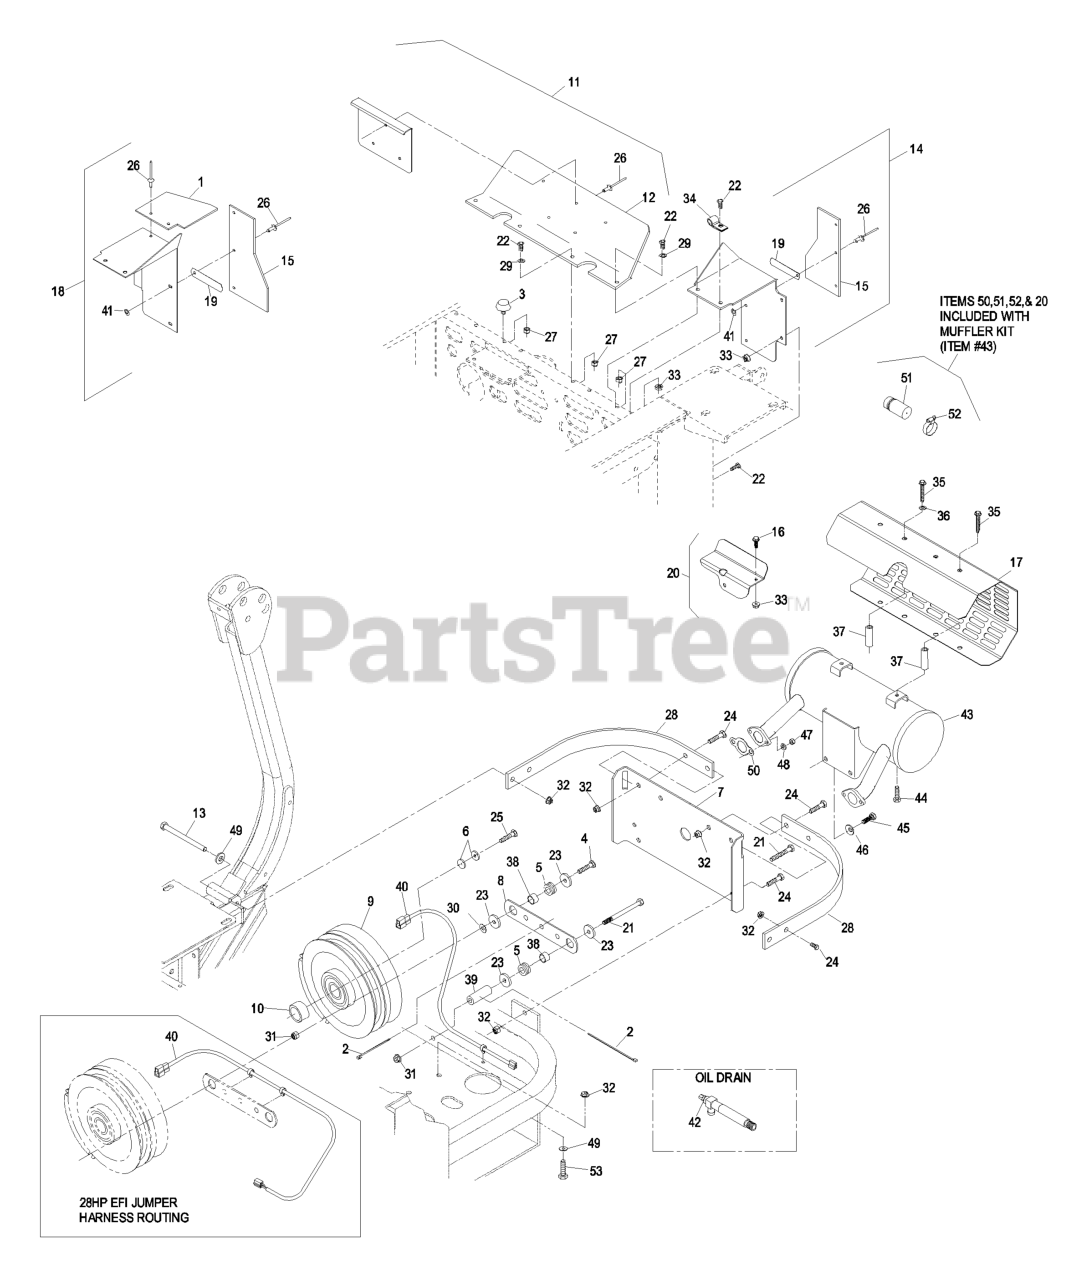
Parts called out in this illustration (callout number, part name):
1	BAFFLE-COOLER, ENGINE
2	TIE-PLASTIC
4	SCREW-HH
5	GROMMET
6	WASHER-SPRING
7	GUARD-CLUTCH
8	STRAP-CLUTCH, BRAKE
9	KIT-CLUTCH
10	SPACER-CLUTCH
12	SHIELD-ENGINE
13	SCREW-HH
15	SHIELD-ENGINE
16	SCREW-HH
17	GUARD-MUFFLER
18	RH SHIELD ASM
19	CLIP-BAFFLE, REAR
20	CABLE HEAT SHIELD KIT
21	SCREW-HH
22	SCREW-HH
24	SCREW-HH
25	SCREW-HH
26	RIVET-POP
27	NUT-LOCK, NI
29	WASHER-FLAT
30	WASHER-FLAT
32	NUT-HHF, WHIZ
34	CLIP-LOOM
36	WASHER-SPRING
39	SPACER-ANCHOR, CLUTCH
40	KIT,CLUTCH JUMPER HARNESS
41	WASHER-FLAT
42	VALVE-OIL DRAIN, LONG
45	SCREW-HH
46	SCREW-HH
47	NUT-HEX
48	WASHER-LOCK
49	WASHER-BELLEVILLE
51	ARRESTER-SPARK
52	CLAMP-MUFFLER
53	SCREW-HH
